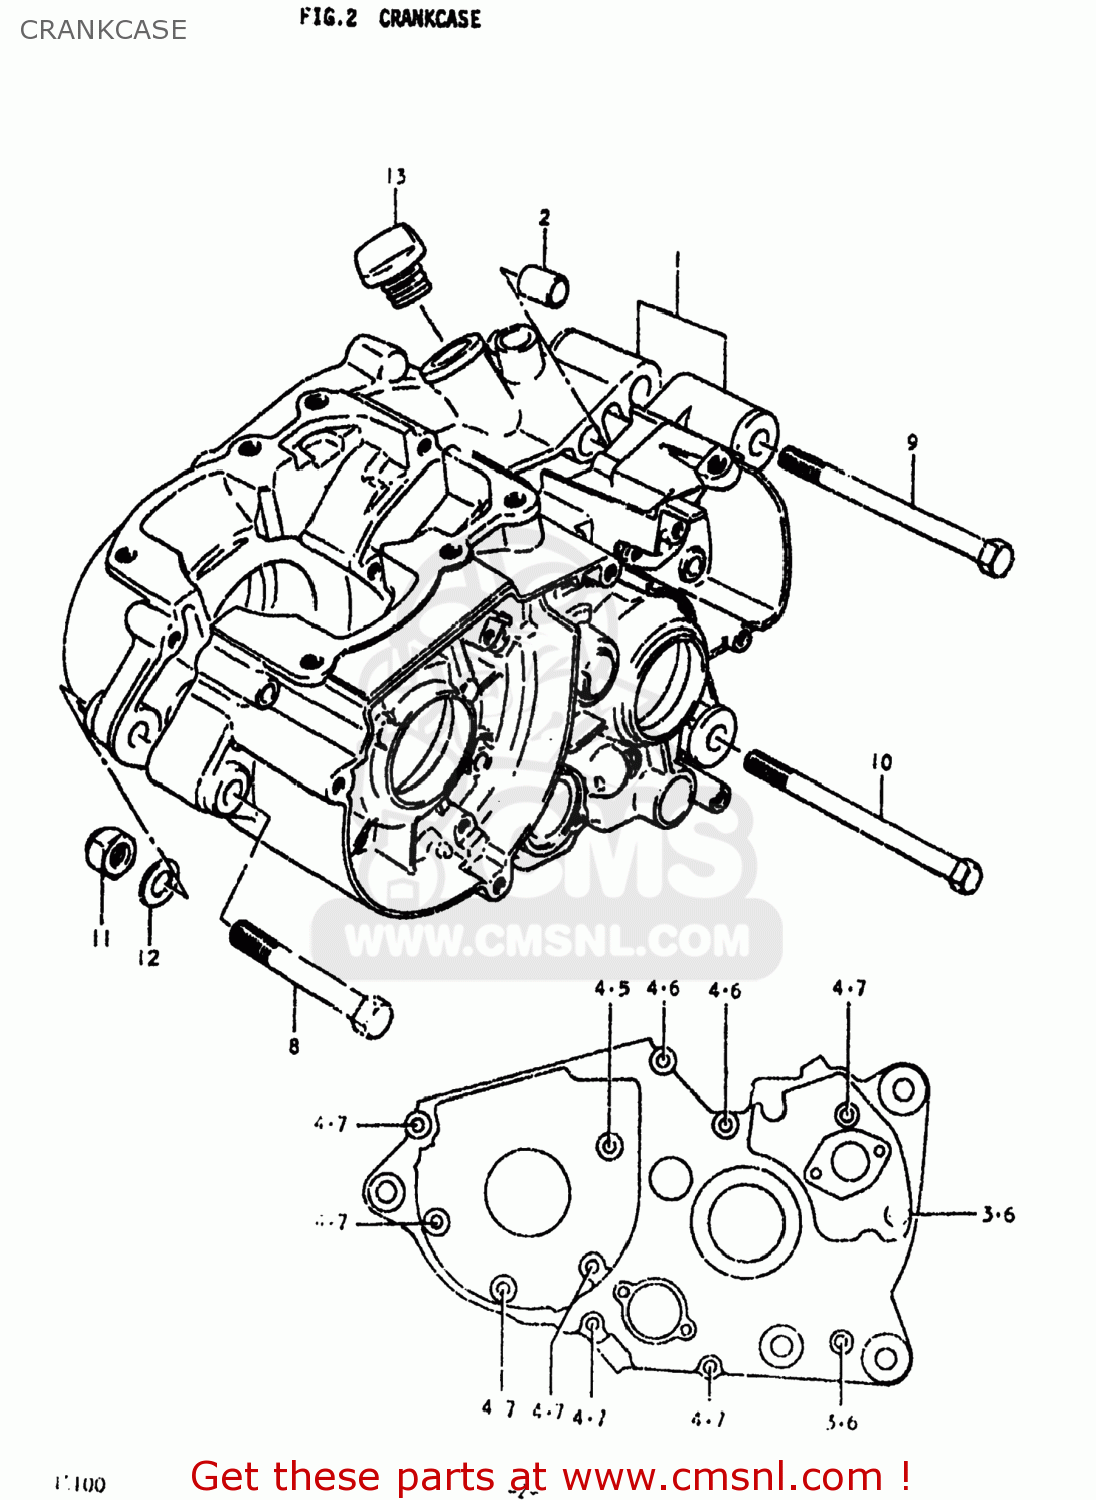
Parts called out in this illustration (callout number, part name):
1	CRANKCASE SET
2	PIN
3	SCREW (6X35)
4	SCREW (6X45)
5	SCREW 6X60
6	SCREW
7	SCREW 6X80
8	BOLT (10X75)
9	BOLT(10X110)
10	BOLT
11	NUT
12	WASHER
